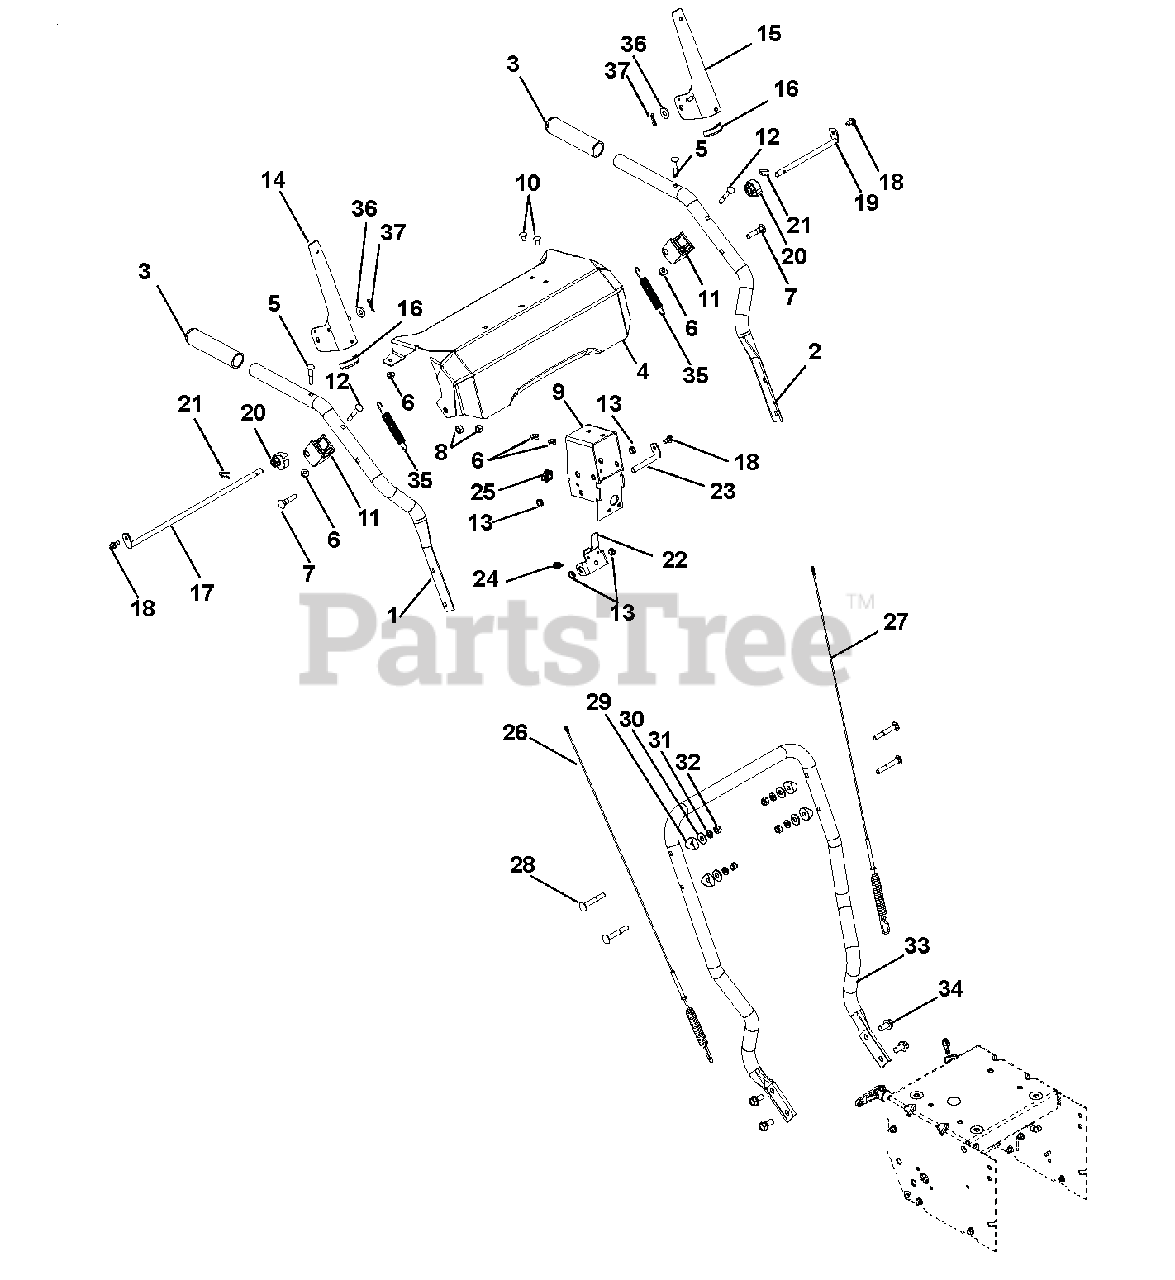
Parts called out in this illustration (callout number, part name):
1	HANDLEBAR, UPPER - RH
2	HANDLEBAR, UPPER - LH
3	HANDLE GRIP
4	PANEL, CONTROL WITH DECAL
5	BLT-RDHDXLSQNK.25-20X1.25 G5ZC
6	@NUT-LK-TOP-FLG .25-20 YWZC
7	BLT-RDHDXLSQNK .31-18X2.0 G5YZ
8	@NUT-LK-CTR .31-18 YWZC
9	WELDMENT, BRACKET INTERLOCK
10	@BLT-RDHDSQNK .25-20X.50 G5YZ
11	BLOCK, CLUTCH PADDLE
12	BLT-RDHDXLSQNK .25-20X2.0 G5YZ
13	BUSHING, POLYLINER-.38 SNAPIN
14	LEVER, CLUTCH-RH
15	LEVER, CLUTCH-LH
16	EDGING, CLUTCH PADDLE - 2.00"
17	ROD, PADDLE MOUNT - LONG
18	SCR-TAP .25-20X.50 HWH TR YWZ
19	ROD, PADDLE MOUNT - SHORT
20	CAM, INTERLOCK
21	PIN, SPRING CLIP
22	BRACKET, INTERLOCK ARM
23	ROD, PIVOT - INTERLOCK
24	SPRING-EXT .047X.438X1.45
25	CRANK BUSHING, NYLON CHUTE BK
26	CABLE, AUGER (SINGLE SPEED)
27	CABLE, UPPER TRACTION (SS)
28	@BLT-RDHDSQNK .31-18X2.25 G5YZ
29	SPACER, HANDLEBAR
30	@WSHR-FL-STL.38X.875X.083 YWZC
31	WSHR-LK .312X.097 HVY YWZC
32	@NUT-LK-NYL .312-18 YWZC
33	HANDLEBAR, LOWER 939 SERIES
34	BLT-SERHFWH .38-16X.75 YWZC
35	SPRING, EXTENSION
36	@WSHR-FL-STL.281X.62X.065 YWZC
37	PIN-HAIR INT .06X.18X.77
